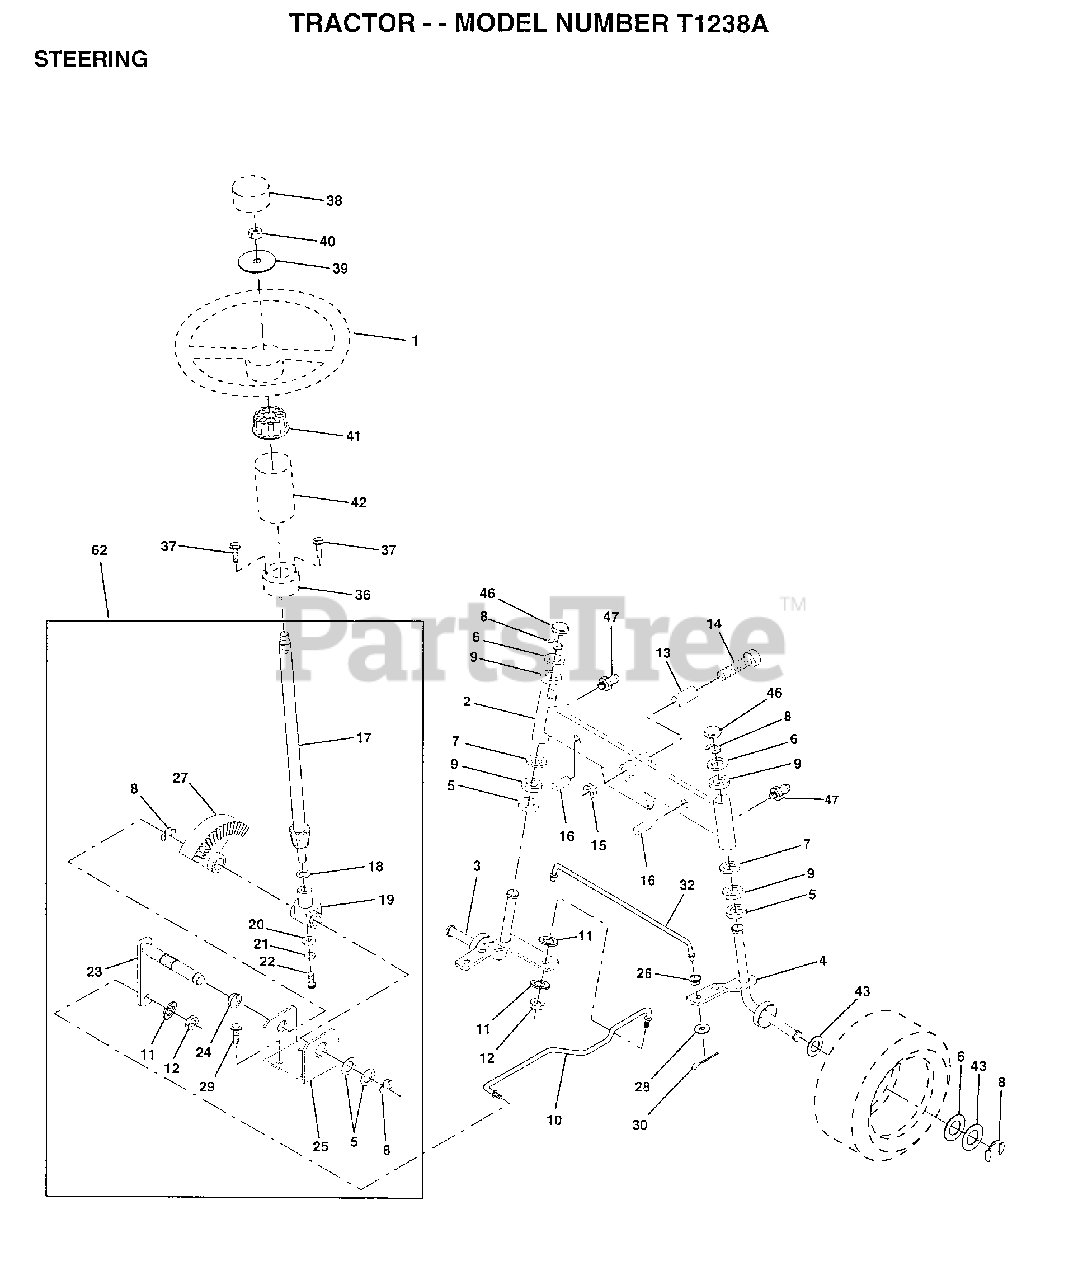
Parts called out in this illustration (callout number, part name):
2	AXLE ASM FRONT
3	SPINDLE LH
4	SPINDLE RH
5	WASHER .T
6	WASHER
8	RING
9	COL. SRTG. BEAR.
11	LOCKWASHER
13	BEARING
14	BOLT HEX 5/8-11
15	"NUT-LOC,FLANGE LT"
16	AXLE PIN
17	SHAFT ASM
18	THRUST WASHER
19	SUPPORT.SHAFT
21	LOCKWASHER
22	SCREW.SCKTHD.CAP
24	NYLINER T
25	"BRKT,STEERING"
26	BUSHING.DRAGLINK
27	GEAR SECTOR
28	WASHER
29	SCREW
30	COTTER PIN
32	TIE ROD
38	ST WHL INSERT CAP
39	WASHER T
40	GRIPCO NUT
41	ADAPTER-WHEEL LT
42	"TUBE, STR SHAFT"
43	WASHER
46	CAP
47	ZERK M
